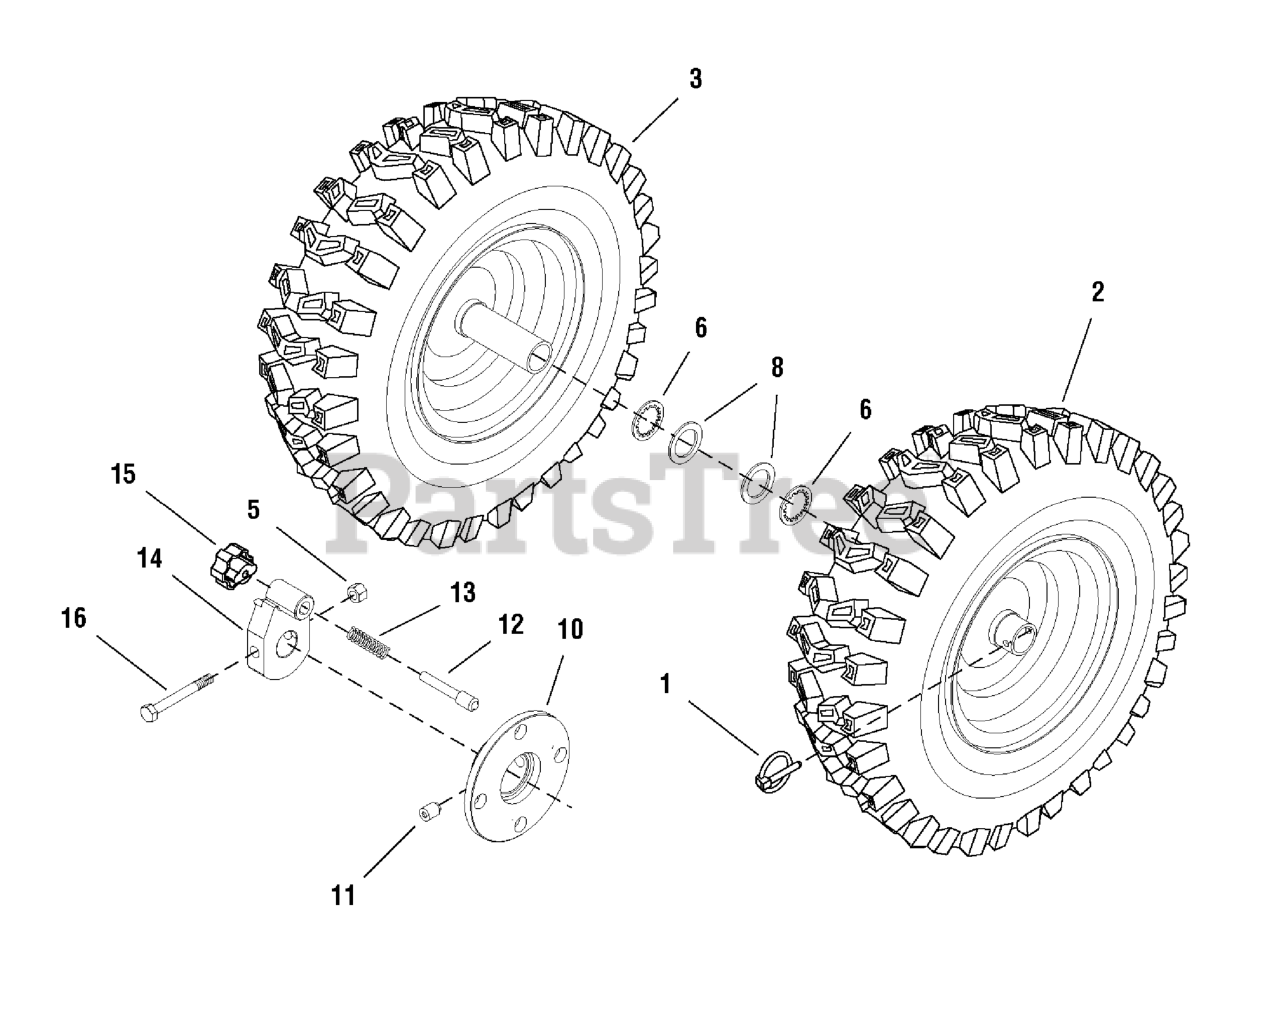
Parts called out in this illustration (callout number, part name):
1	PIN, Klik
2	WHEEL & TIRE ASSEMBLY, L.H.
2	WHEEL & TIRE ASSEMBLY, L.H. SNOW XTRAC 16 x 4.8-8
3	WHEEL & TIRE ASSEMBLY, R.H.
3	WHEEL & TIRE ASSEMBLY, R.H. SNOW XTRAC 16 x 4.8-8
5	NUT, Hex Lock ESNA Light, 1/4-20 NC3B Black
6	RETAINING RING, Extertal, #75 0.750 Self Lock
8	WASHER, Flat .765 x 1.12 x .06 YZ
10	DISC, Wheel Lock
11	SCREW, 3/8-16 x 1/2 Hex-18
12	PIN, Wheel Lock 1/4-20 0.7
13	SPRING, Compression
14	HUB, Wheel Lock Centered
15	KNOB, Wheel Lock
16	CAPSCREW, 1/4-20 x 2-1/4 Hex Head GR
